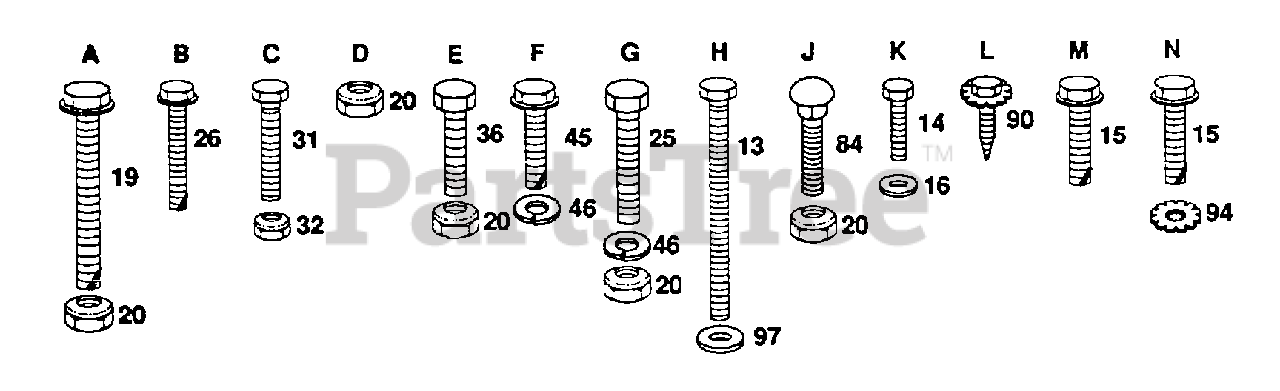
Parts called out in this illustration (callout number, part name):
13	"BOLT,HEX"
14	BOLT
15	SCREW
16	LOCKWASHER
19	BOLT
25	BOLT
26	SCREW
31	BOLT
45	SCREW
46	WASHER
84	BOLT
94	LOCKWASHER
97	WASHER T
